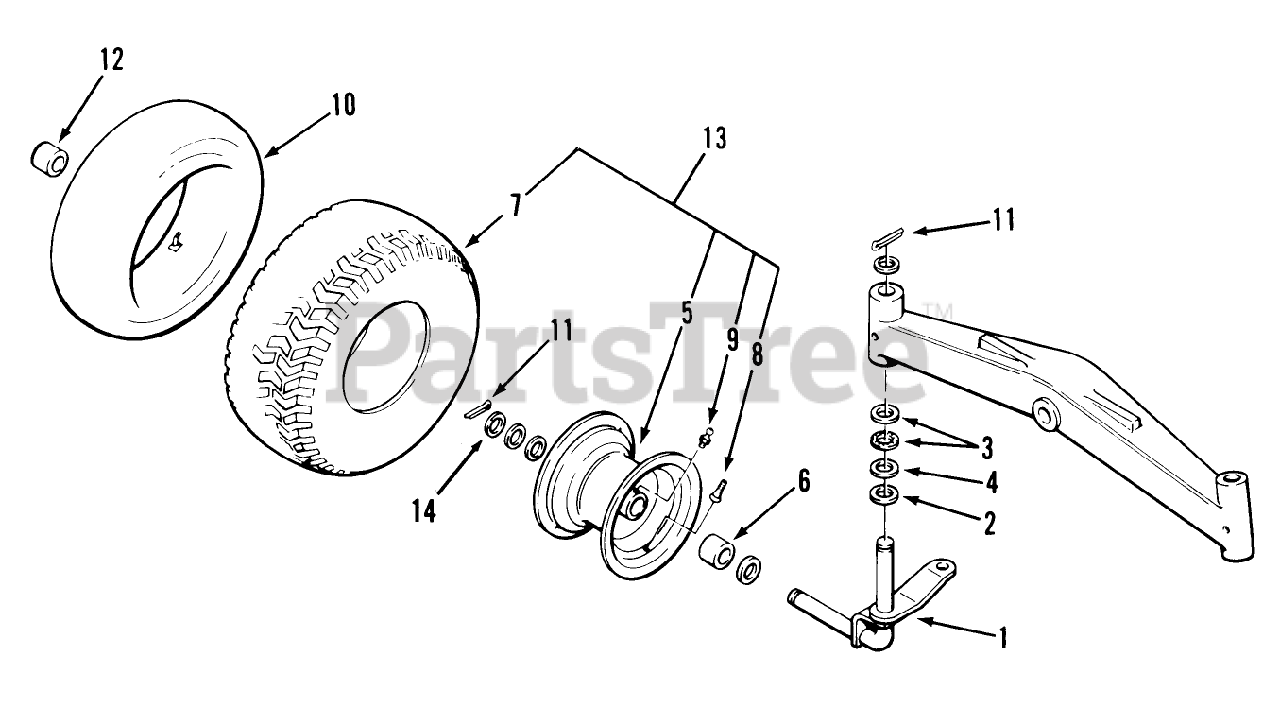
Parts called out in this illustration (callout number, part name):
1	Spindle R.H.
2	Race Thrust
3	WASHER-SLIP
4	WASHER
5	WHEEL
6	BEARING-RADIAL FLNGE
7	TIRE TURF SAVER 16X6.50-8
8	VALVE
9	ZERK-GREASE
10	TUBE-INNER
11	COTTER PIN-4
12	CAP-HUB
13	Wheel and Tire Assembly
14	WASHER-WHEEL
